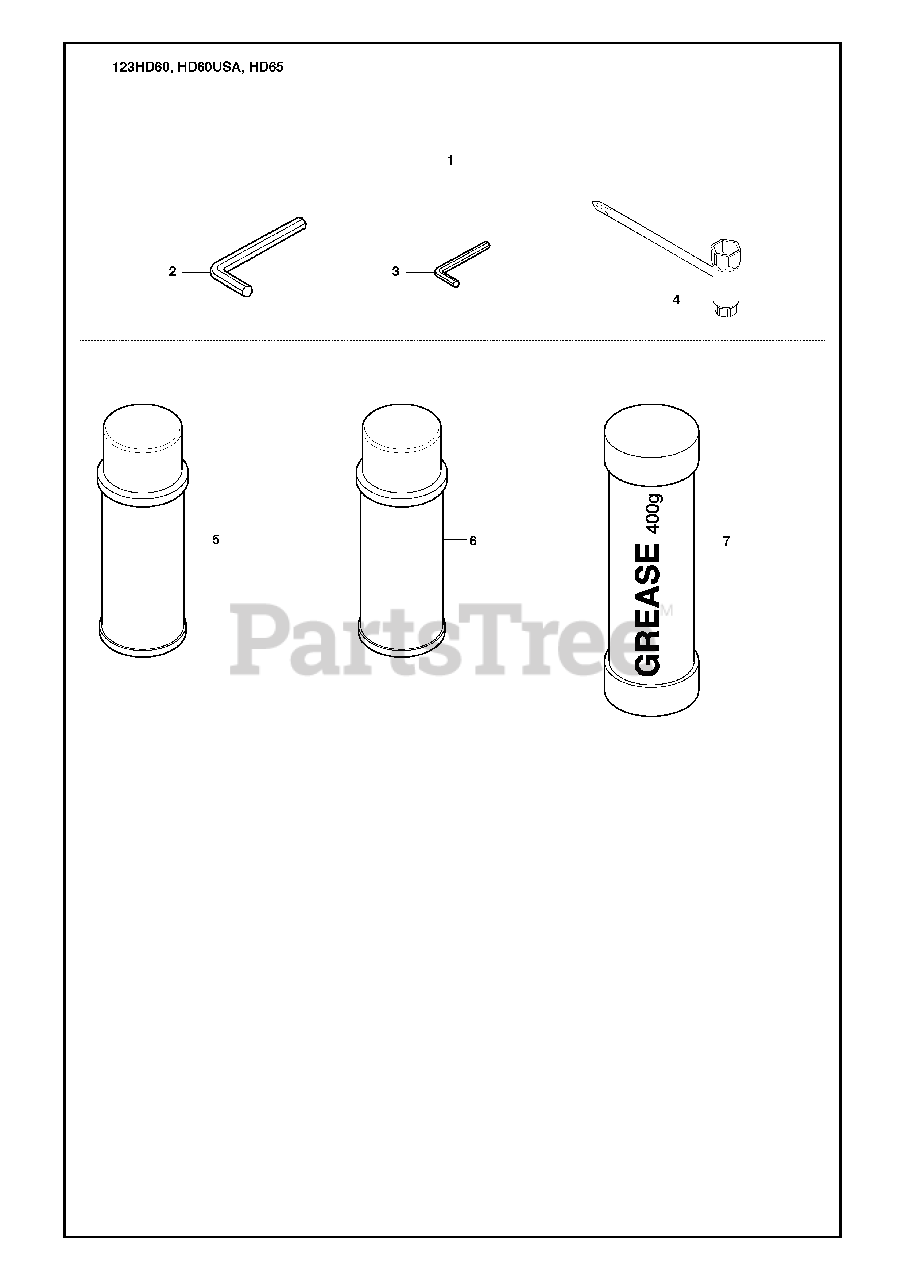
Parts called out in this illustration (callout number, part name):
1	ACCESSORY BAG
4	COMBINATION WRENCH
5	UL 22 - 12 PACK
6	CUTTER BAR LUBE/12 PACK UL21
7	GREASE 400 GRAMS
